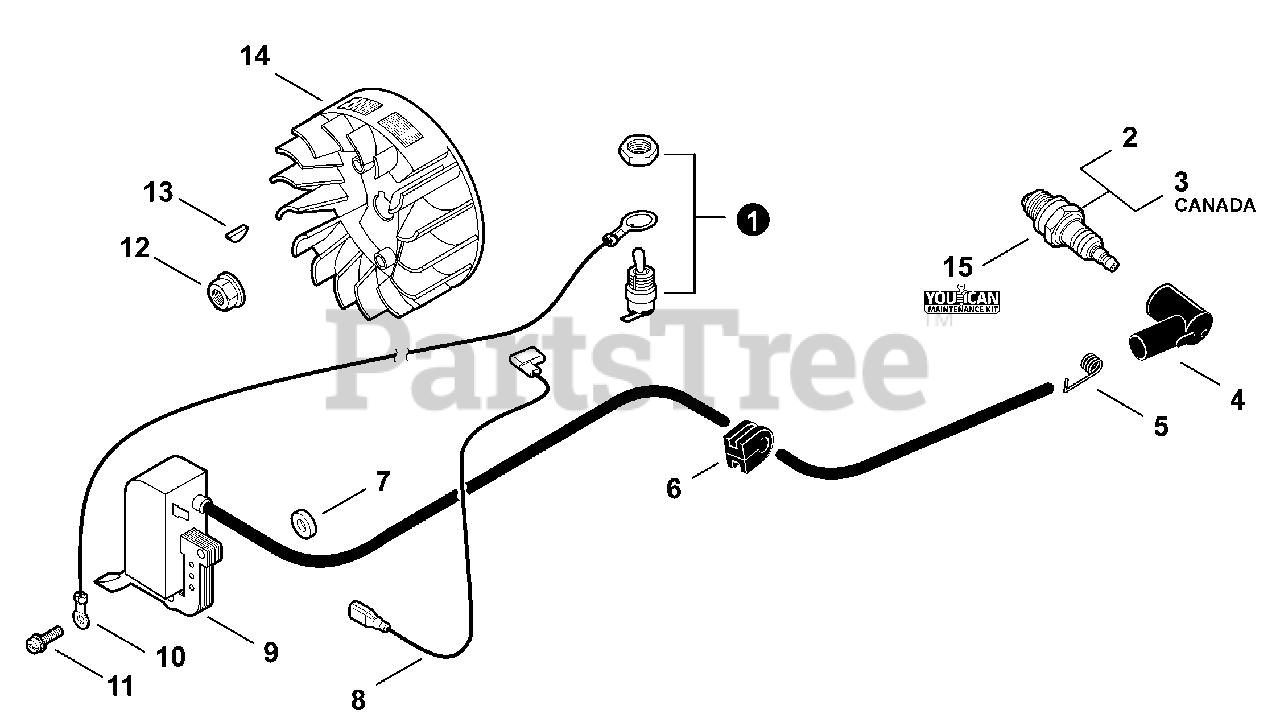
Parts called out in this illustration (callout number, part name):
1	SWITCH, ON-OFF
2	SPARK PLUG - BPM8Y
3	SPARK PLUG - BPMR8Y
4	CAP, SPARK PLUG
5	TERMINAL, SPARK PLUG
7	WASHER 5.2×12×3
8	LEAD - IGNITION L= 95
9	COIL, IGNITION
10	LEAD - GROUND L= 100
11	SCREW 5×22
12	NUT, FLANGE M8
13	KEY, WOODRUFF
14	FLYWHEEL
15	TUNE-UP KIT - YOUCANT
